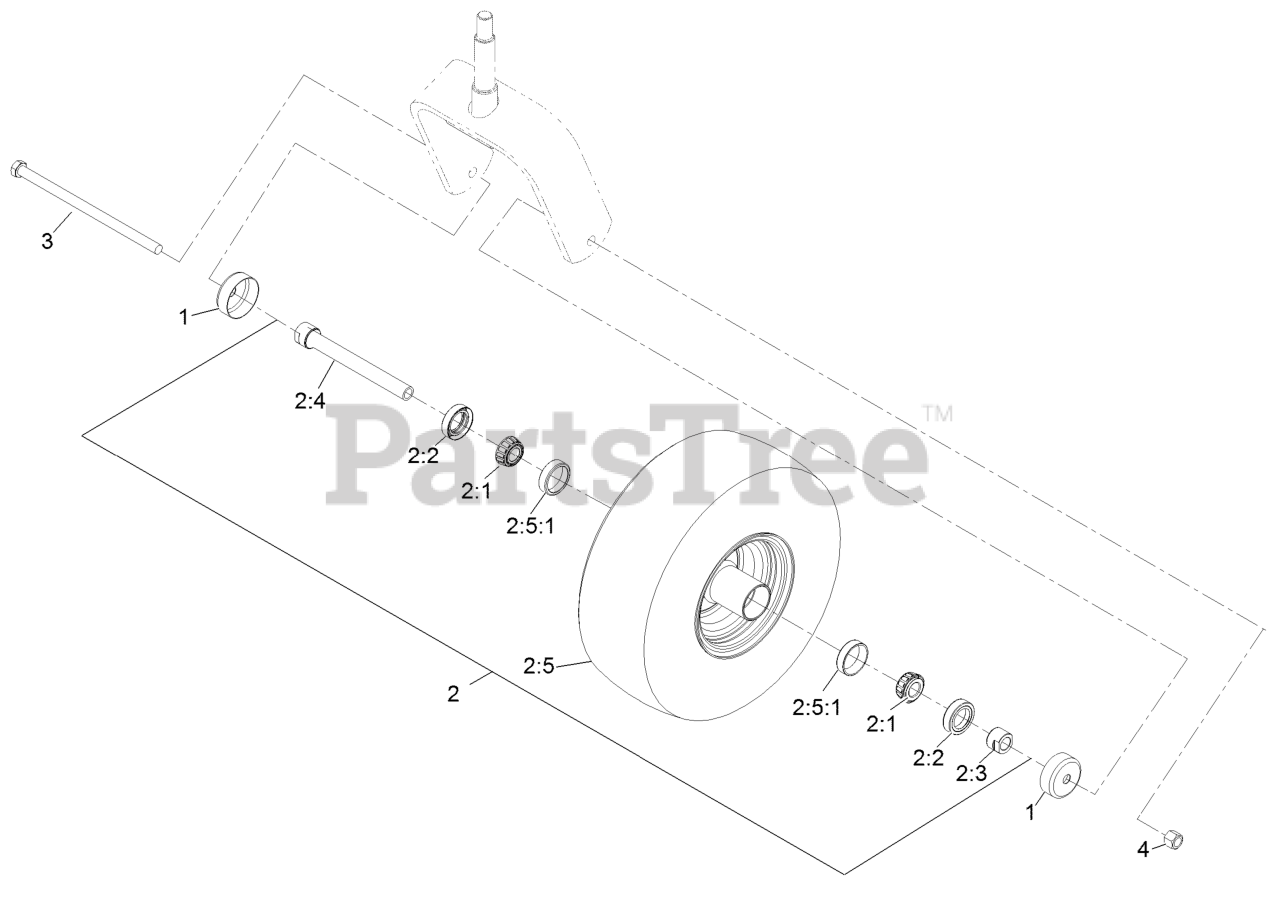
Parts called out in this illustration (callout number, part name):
1	GUARD-SEAL
2	Wheel And Tire ASM
2:1	BEARING-CONE, TAPERED ROLLER
2:2	SEAL-CASTER
2:3	SPACER-NUT
2:4	AXLE CASTER ASM
2:5	Wheel And Tire ASM
2:5:1	BEARING-CUP
3	SCREW-HH
4	NUT-LOCK, NI
